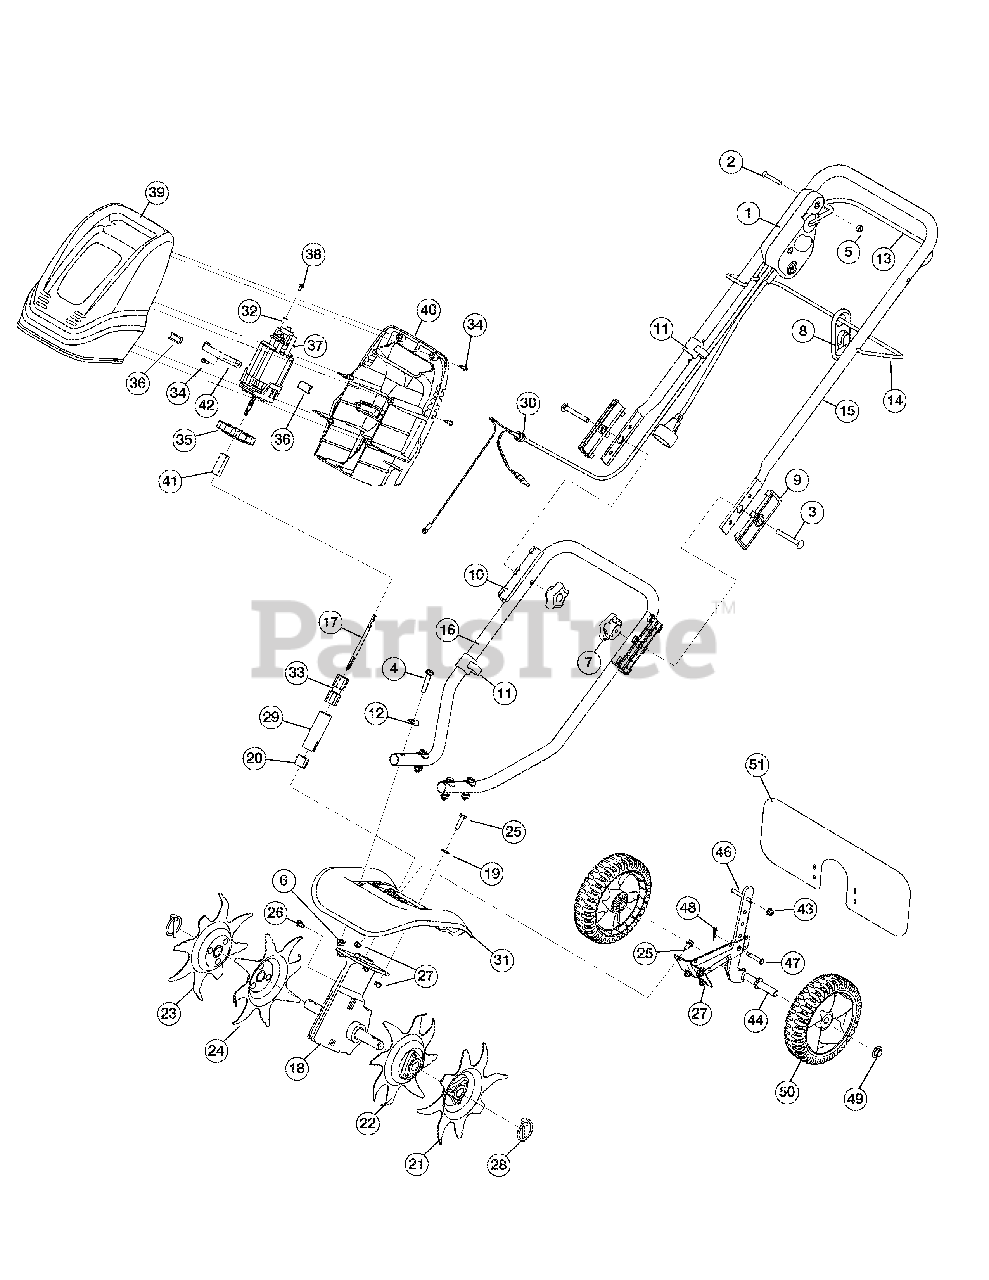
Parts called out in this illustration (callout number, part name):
1	Switch Assembly
4	Screw
8	Cord Retainer
9	Upper Handle Insulator
10	Lower Handle Insulator
11	Cable Guide
12	Saddle Washer
13	Control Bail
15	Upper Handle
16	Lower Handle
17	Flex Shaft
18	Gearbox
19	Washer
20	Sleeve
21	Outer Tine Assembly
22	Inner Tine Assembly
23	Outer Tine Assembly
24	Inner Tine Assembly
25	Screw
26	Bolt
28	Lynch Pin
29	Boom Tube
30	Cord Bushing
31	Tine Shield
32	Lock Washer
33	Flex Tube Assembly
36	Motor Pad
37	Motor Assembly
39	Front Motor Cover
40	Rear Motor Cover
41	Motor Hub
42	Motor Strap
43	Bracket Assembly
44	Wheel Support Bracket Assembly
46	Belt Guard Pin
47	Clevis Pin
48	Cotter Pin
49	Push Cap
50	Wheel (includes 49)
51	Debris Shield
